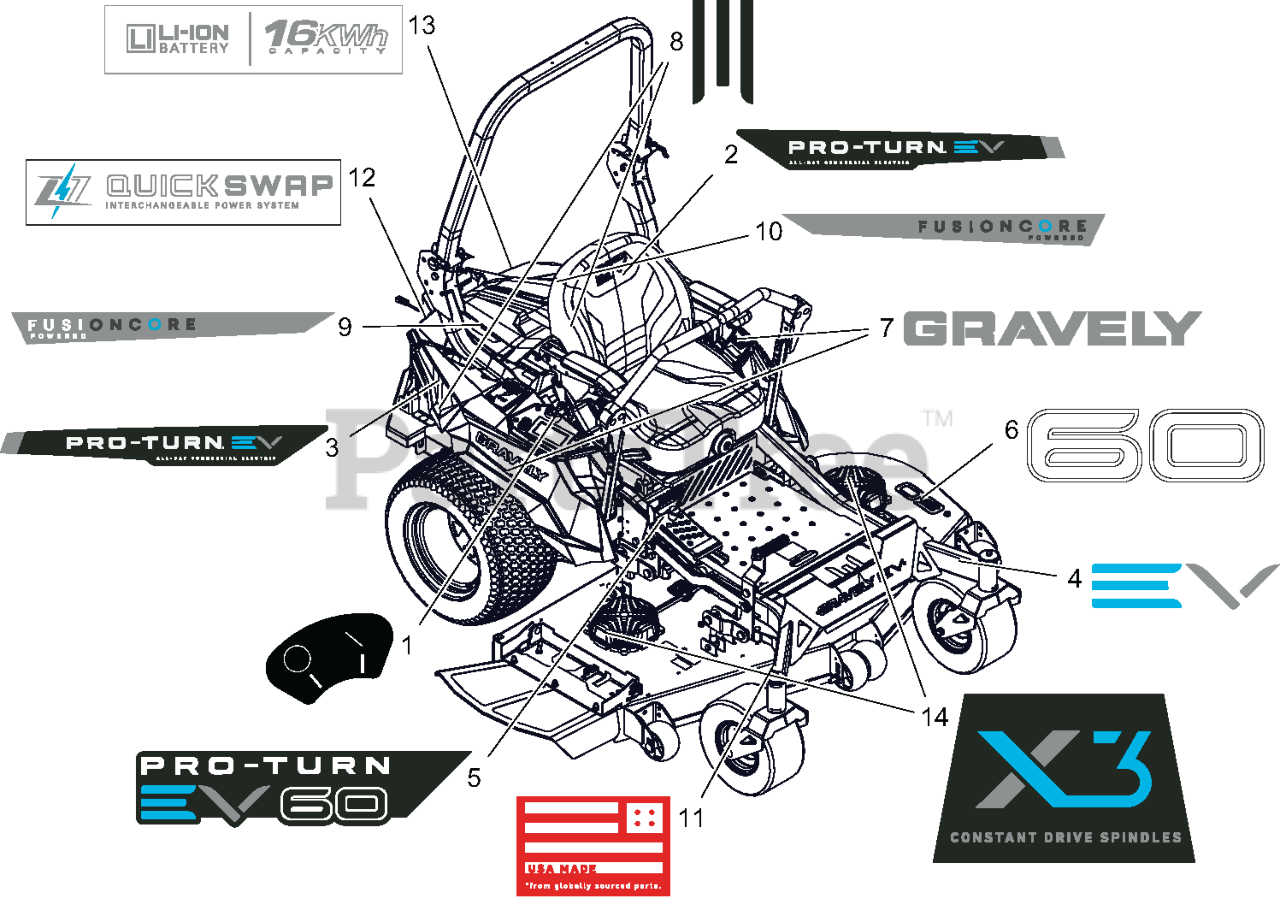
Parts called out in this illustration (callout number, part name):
1	DECAL, KEY SWITCH - 2POS
2	DECAL, FENDER - LH
3	DECAL, FENDER - RH
4	DECAL, FRONT FORK
5	DECAL, KICK PLATE
6	DECAL, DECK - 60"
7	DECAL, GRAVELY LOGO
8	DECAL, STRIPE
9	DECAL, FUSION CORE - LEFT
10	DECAL, FUSION CORE - RIGHT
11	DECAL, USA MADE
12	DECAL, QUICK SWAP -HATCH
13	DECAL, LI- ION - HATCH
14	DECAL, DECK MOTOR
